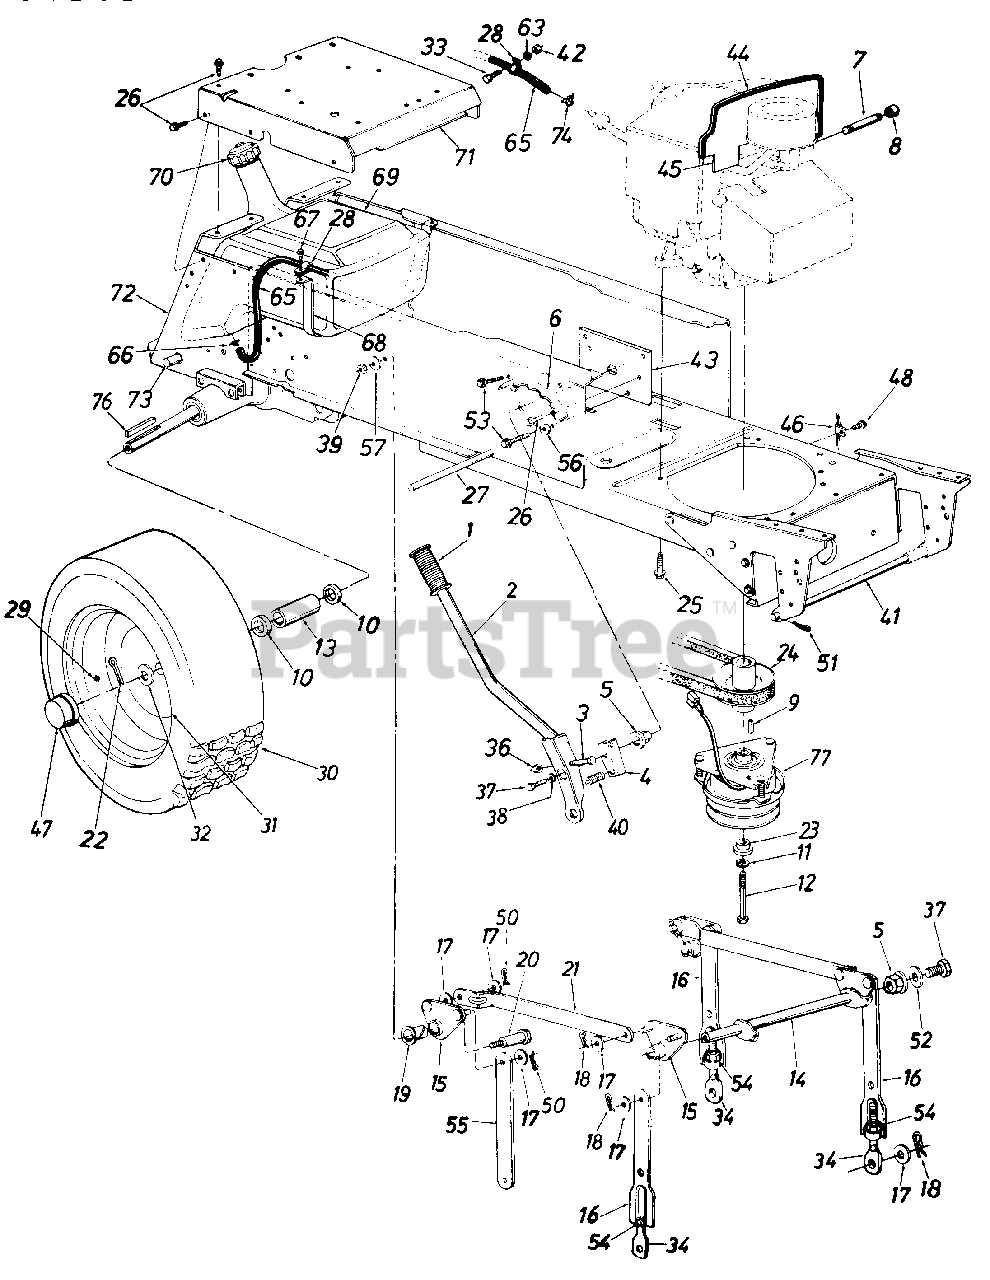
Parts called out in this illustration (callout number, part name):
1	Grip
2	Lift Handle Ass'y.
3	Hex Bolt 5/16-18 x 1.5" Lg.
4	Lift Shaft Drive
5	Plastic Hex Brg. 518" I.D.
8	Pipe Cap 3/8-18 Npt.
9	Sq. Key 114" x 114" x 1.50" Lg.
10	Fl-Wash. 1.03" I.D. x 1.62" O.D.
11	L-Wash. 7/16" I.D.
12	Hex Bolt 7/16-20 x 3.75" Lg.
13	Spacer 1.0" I.D. x 1.25" O.D.
14	Lift Shaft Ass'y.
15	Lift Pivot Brkt. Ass'y.
17	Fl-Wash. 112" I.D. x 1.00" O.D. x .090"
18	Hairpin Cotter
19	Nyliner 518" I.D. x .88" Lg.
20	Shld. Bolt 518" Dia. x .96" Lg. 3/8-16
23	Shoulder Spacer
24	Engine Pulley
25	Hex Wash. Hd. Scr. 3/8-16 x 1.25" Lg.
26	Hex Thd. Rolling Scr. 5/16-18 x . 75 " Lg .
27	Running Board Rod
28	Clamp
29	Air Valve
33	Hex Bolt 1/4-20 x .62" Lg.
34	Eye Bolt Adj. Link 1/2-13 Thd.
36	Hex Cent. L-Nut 5/16-18 Thd.
37	Hex Scr. 5/16-24 x .62" Lg.
38	L-Wash. 5/16" I.D.
39	Hex Top L-Nut 3/8-16 Thd.
40	Compression Spring
41	Deck Connecting Rod
42	Hex Nut 1/4-20 Thd.
45	Heat Shield
46	Mounting Clamp
47	Hubcap
48	Hex Wash. Hd. TT-Tap Scr. 1/4-20 x .5" Lg.
50	Cotter Pin .09 Dia. x 1.0" Lg.
51	Int. Cotter Pin
52	Flat Wash. .34" I.D. x 1.12" O.D. x .125"
53	Hex Wash. Hd. AB-Tap Scr. 5/16-24 x .5" Lg.
54	Hex Nut 1/2-13 Thd.
56	Fl-Wash..344" I.D.
57	Bell-Wash. .4" I.D. x 1.13" O.D.
63	L-Wash. 1/4" I.D.
65	Fuel Line 50" Lg.
66	Hose Clamp
67	Hex AB-Tap Scr. 1/4 x .62" Lg.
68	Fuel Tank Strap
69	Gas Tank
70	Gas Gauge
71	Seat Plate
74	Hose Clamp
76	Sq.-Key 1/4" x 3.0" Lg.
77	Electric Clutch
